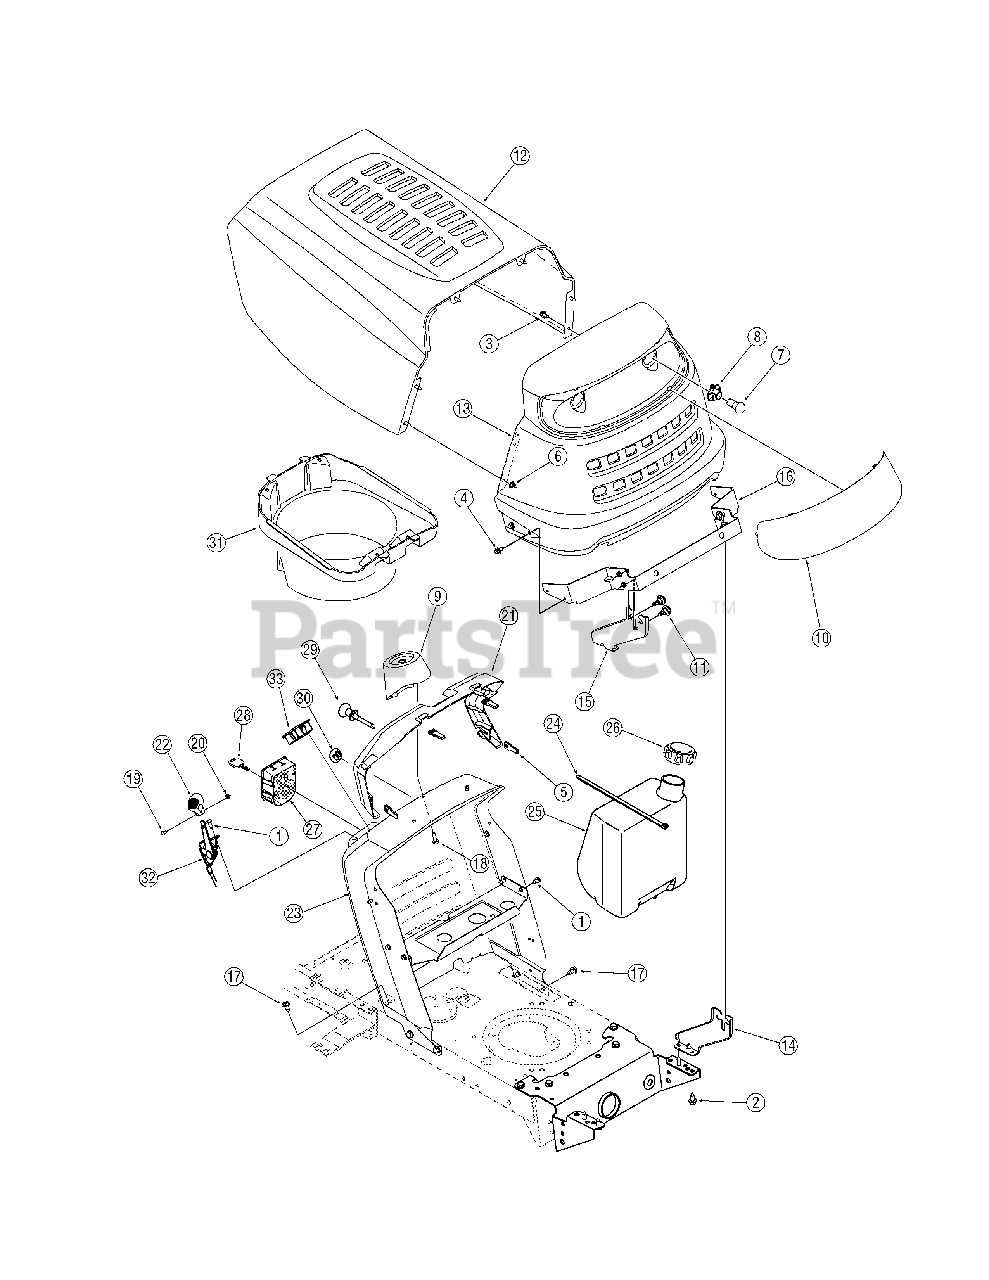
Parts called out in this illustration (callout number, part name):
1	Screw, 1/4-20, 0.500
2	Screw, 5/16-12, 0.750
3	Screw, 1/4-20, .620, Gr5
4	Screw, 1/4-20, .625
5	Nut, 1/4-20, Speed U-type
6	Nut, Flange Lock, 1/4-20, Gr F, Nylon
7	Headlamp, 12V
8	Headlamp Socket
9	Collar, Dash
10	Lens
11	Screw, Shoulder, .43 x.29, 5/16-18
18	Screw, 1/4-15, 0.750
19	Screw, Machine, #8-32, 0.375
20	Nut, Hex, #8-32, Gr A
21	Support, Steering
22	Knob, Control
24	Cable Tie, 34.75
25	Fuel Tank, 1.5 gal.
26	Fuel Tank Cap
27	Module, Ignition Switch
28	Key
29	Choke Control, 37.5"
31	Plenum
32	Throttle/Choke Control, 25"
32	Throttle Control, 39"
33	Ammeter
